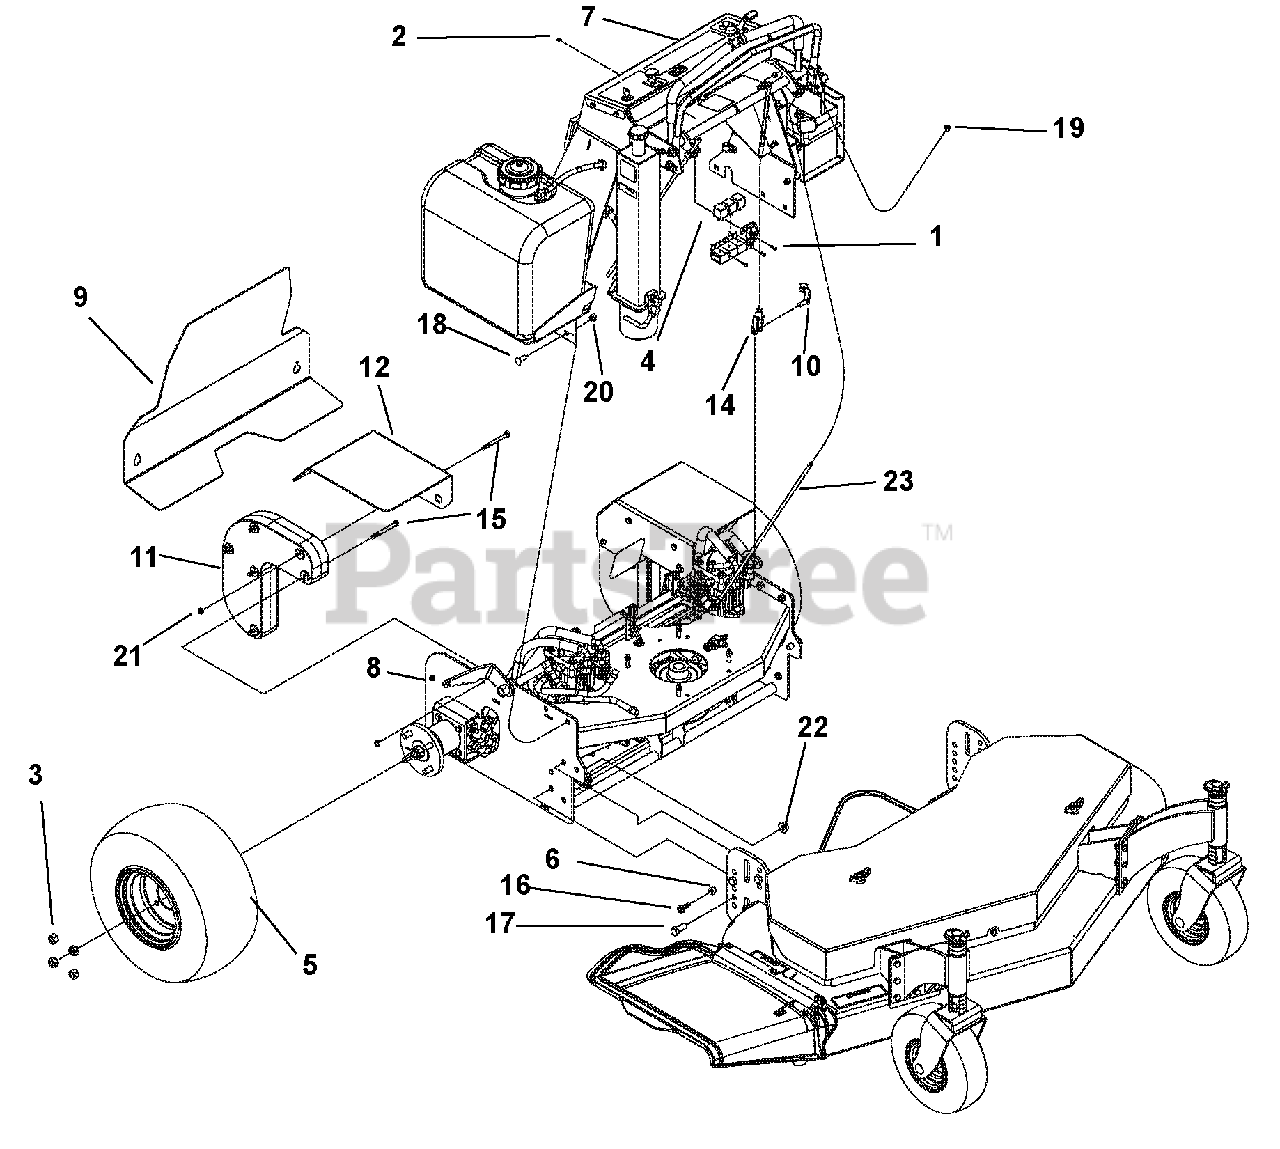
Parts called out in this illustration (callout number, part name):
1	Bolt, Hex 8-32 x .5
2	Nut, Locking, Nylon 8-32
3	Nut, Lug .5-20
4	Relay, ISO Mini Electric
5	Assembly, Tire/Wheel 18/8.5 x 8
6	Spacer, .625 x .120 x .400
7	Assembly, Console
8	Power Unit
9	Foot Guard w/Decals S/O
10	Pin, CVS SPG 3/8" Yoke
11	Weight, Cast Drilled
12	Fender, LH S/O
13	Fender, RH S/O
14	Yoke, 3/8-24 RH Adjustable
15	Bolt, .31-18 x 3.25 Grade 5
16	Bolt, .38-16 x 1.00 Grade 8
17	Bolt, .50-13 x 1.25 Grade 5
18	Bolt, Round Head Square Neck .38-16 x 1.00
19	Nut, Hex .312-24
20	Nut, Locking, .375-16
21	Nut, Locking, Nylon .312-18
22	Nut, Locking .50-13
23	Control Rod
